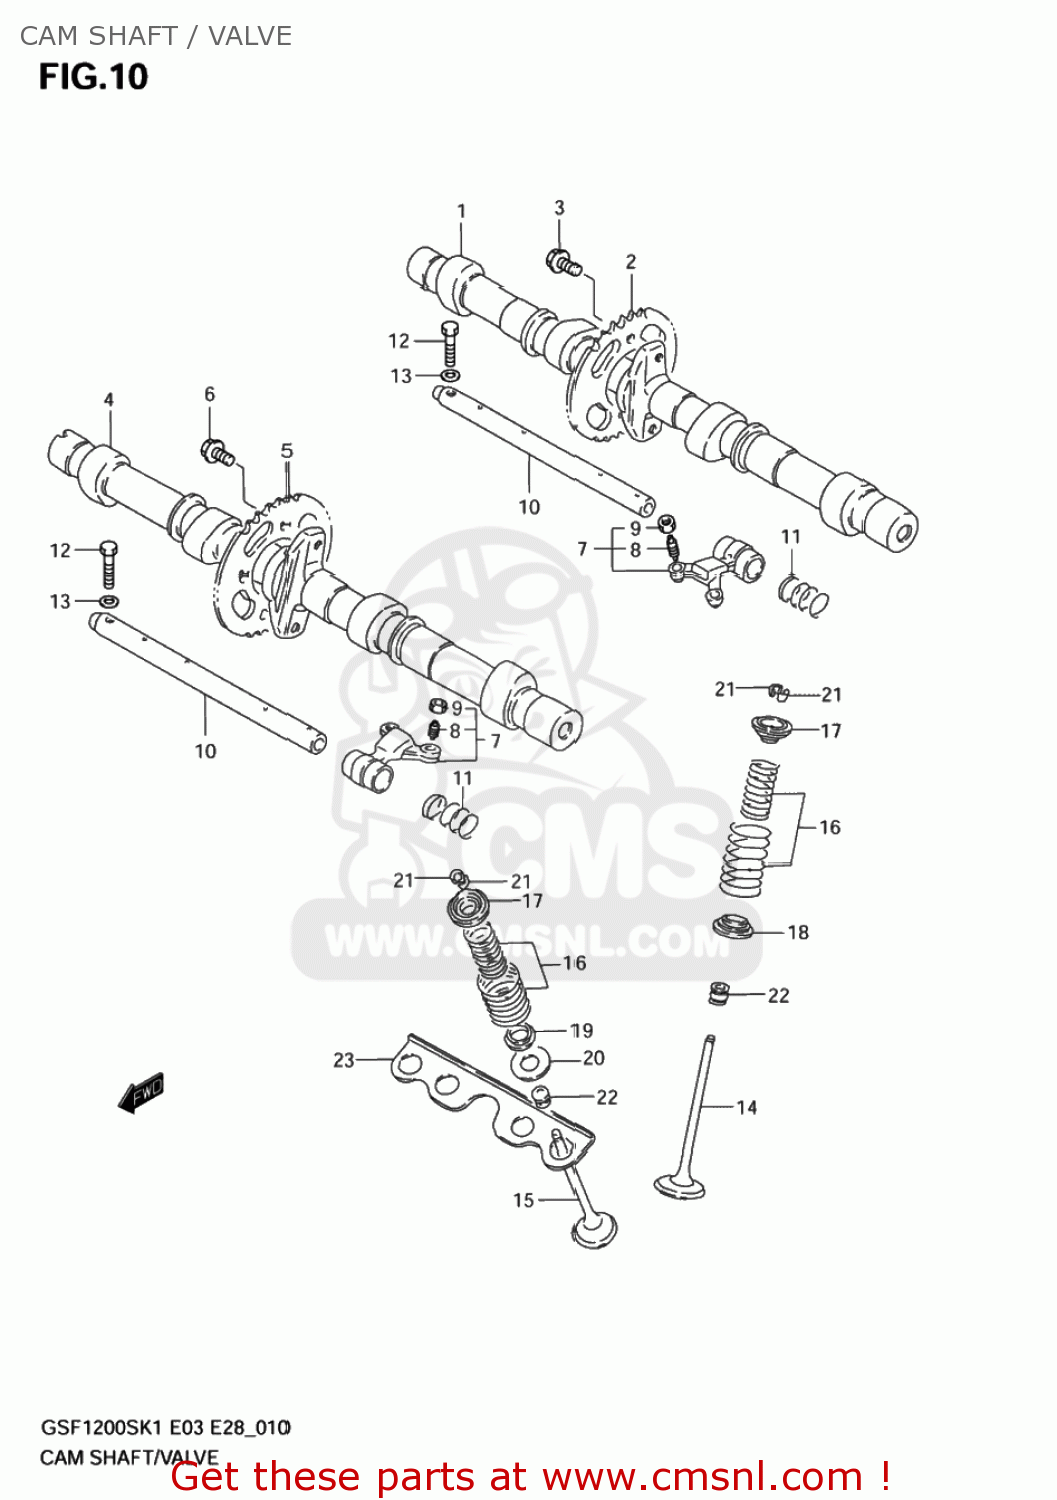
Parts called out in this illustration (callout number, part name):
1	CAMSHAFT,INTAKE
2	SPROCKET,CAMSHAFT
3	BOLT(7X11)
4	CAMSHAFT,EXHAUST
5	SPROCKET,CAMSHAFT
6	BOLT(7X11)
7	ARM,VALVE ROCKER
8	SCREW,TAPPET ADJUSTING
9	NUT,TAPPET ADJUSTING
10	SHAFT,VALVE ROCKER ARM
11	SPRING
12	BOLT(6X30)
13	WASHER
14	VALVE,INTAKE
15	VALVE,EXHAUST
16	SPRING SET,VALVE
17	RETAINER,VALVE SPRING
18	SEAT,VALVE SPRING
19	SEAT,VALVE SPRING EXH INNER
20	SEAT,VALVE SPRING EXH OUTER
21	COTTER VALVE
22	SEAL,OIL(5X10X9.7)
23	PLATE,VALVE SEAT
